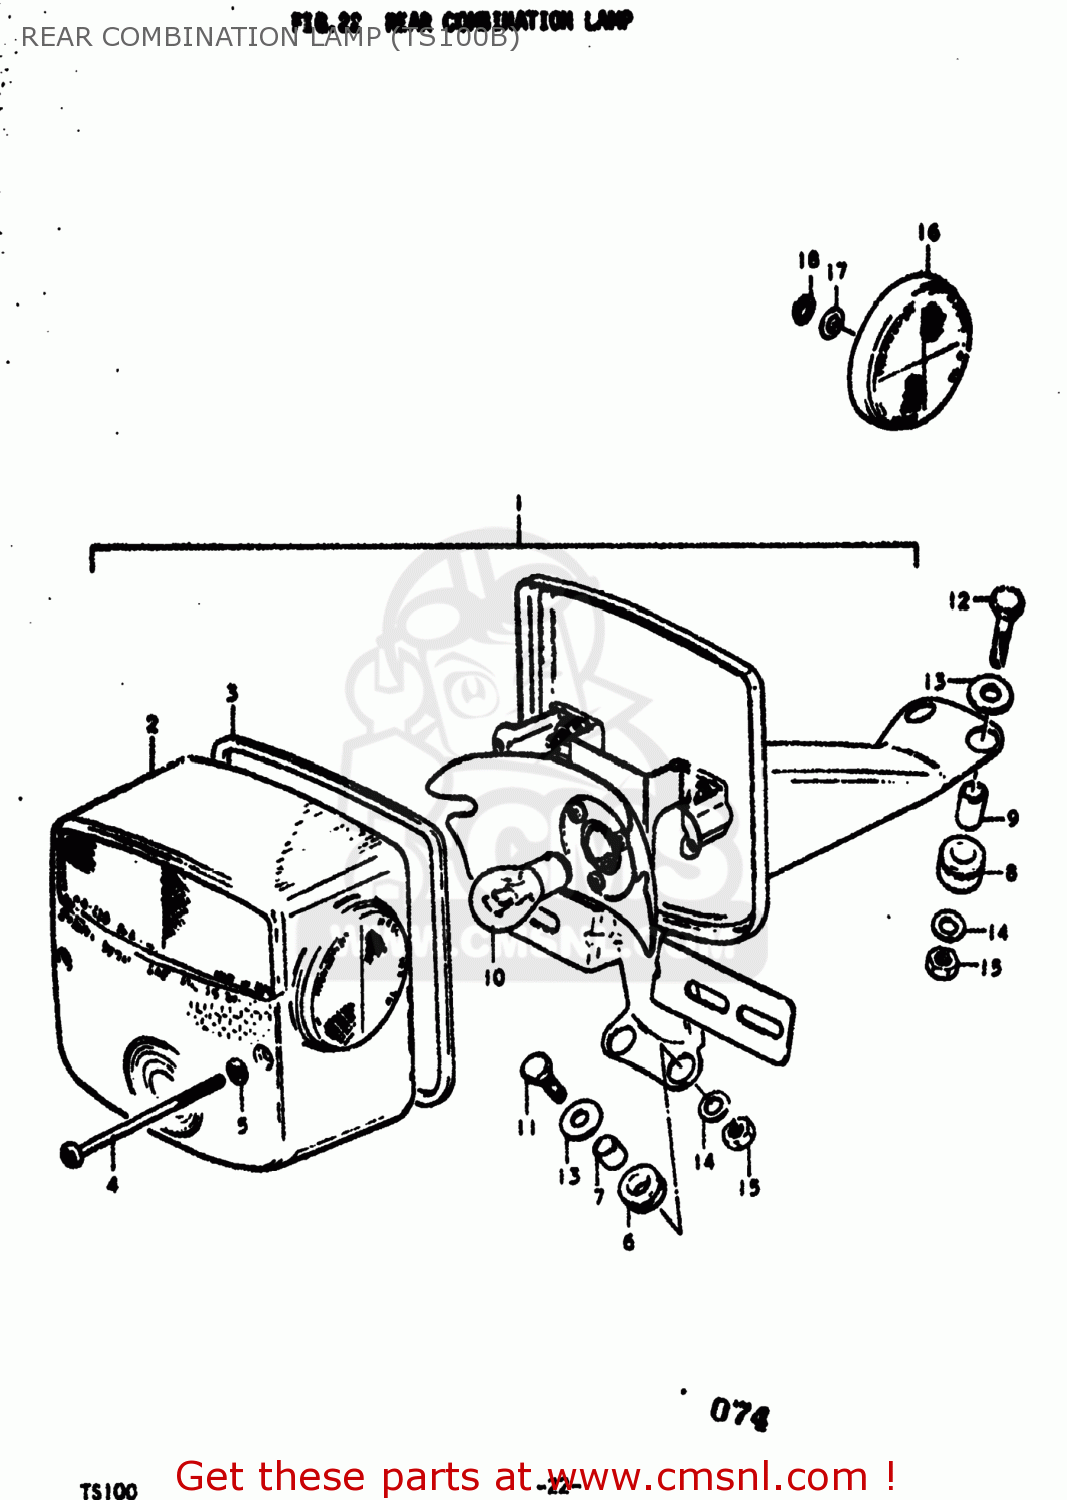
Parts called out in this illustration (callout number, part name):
1	LAMP ASSEMBLY,REAR COMBINATION
2	LENS,REAR COMBINATION LAMP
3	GASKET (NAS)
4	SCREW
5	GASKET (NAS)
6	CUSHION
7	SPACER,REAR COMBINATION LAMP
8	CUSHION
9	SPACER,REAR COMBINATION LAMP
10	BULB(6V32/3CP,STANLEY)
11	BOLT
12	BOLT
13	WASHER (6.5X20X1.2)
14	WASHER
15	NUT
16	REFLEX REFLECTOR,FR
17	WASHER
18	LOCK WASHER
